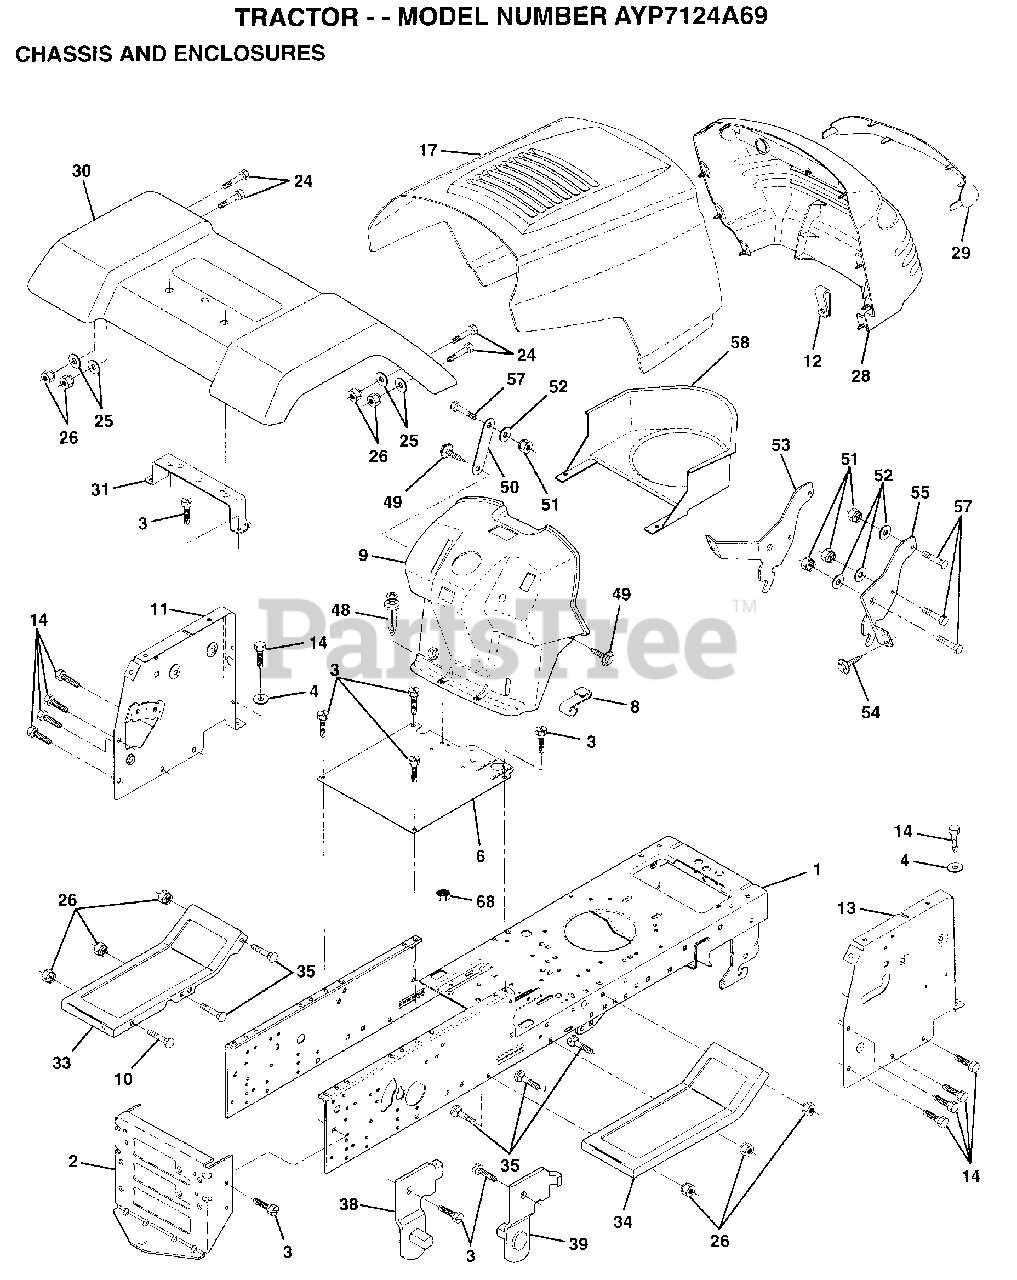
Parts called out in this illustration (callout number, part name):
1	CHASSIS.WLD.11GA
3	SCREW
4	WASHER
8	"CLIP,INSULATOR"
11	PANEL.DASH.LH.
12	CLIP.TINNERMAN
13	PANEL.DASH.RH
14	SCREW LT
24	BOLT
25	WASHER
26	NUT
29	LENS GRILLE
30	FENDER
31	BRKT FENDER
33	FOOTREST LH
34	FOOTREST RH
35	BOLT
38	BRACKET ASM LH
39	BRACKET ASM RH
48	RIVET.PUSH.PLATE
49	SCREW HEX CRT
50	BRACE SUPT DASH
51	NUT
52	WASHER
53	BRACKET.GRILLE.LH
55	BRACKET.GRILLE.RH
58	DUCT AIR 12-15H
68	NUT
